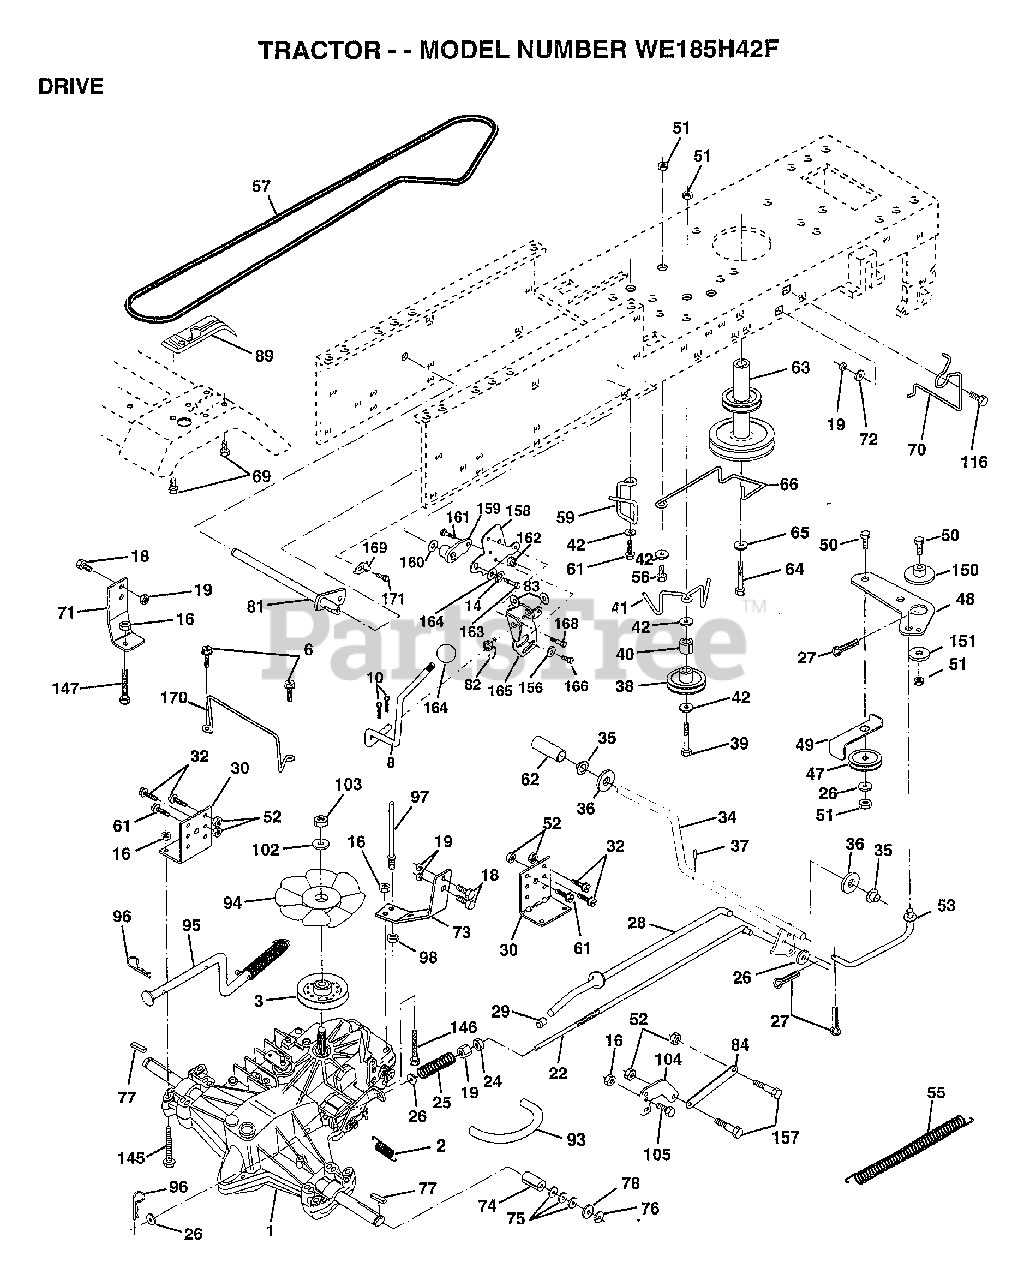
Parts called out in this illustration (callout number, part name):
2	SPRING RET BRAKE
3	PULLEY.TRANSAXLE
8	ROD.SHIFT.FENDER.ADJ.LT.CRD
10	PIN COTTER 1/8
14	LOCKWASHER
16	NUT
18	BOLT
19	NUT
21	KNOB T (1/2-HOLE)
22	ROD.BRAKE.HYDRO.
24	NUT
25	SPRING ROD LT
26	WASHER
27	COTTER PIN
28	ROD.BRAKE.PARK.LT
29	PLUNGER CAP T
30	TRANSAXLE MTG BKT
32	BOLT
34	SHAFT ASM-PEDAL F
35	NYLON BEARING
36	WASHER LT
38	FLAT IDLER PULLEY
39	BOLT
40	SPACER T
41	"KEEPER,BELT.IDLER FLAT"
42	WASHER
48	BELLCRANK.CLUTCH
49	RETAIN BELT
53	"LINK, CLUTCH T"
55	"SPRING, RETURN LT"
57	"BELT.GD DRV 82"""
59	KEEPER BELT CNTSP
61	SCREW
62	PEDAL COVER T
63	PULLEY.ENGINE
64	BOLT
65	LOCKWASHER
66	KEEPER-BELT
69	SCREW HEXWSH H-L
70	KEEPER BELT ENG
71	STRAP TORQ LH HYD
72	WASHER
73	"STRAP-TORQUE,RH"
74	SPACER SPLIT
75	WASHER
76	E-RING LT
77	SQUARE KEY
78	WASHER
81	SHAFT.ASM.CROSS
82	"SPRING,TORSION"
83	WASHER
84	LINK.TRANSAXLE.LT/YT
89	CONSOLE.SHIFT.LT
93	"LINE FUEL HYD 4"""
94	"FAN 7"" HYDRO"
96	RETAINER M
97	BOLT KEEPER RH
98	NUT
102	WASHER BELLEVILLE
104	ARM CONTROL HYDRO
105	SCREW CAP 5/16-18
116	BOLT RDHD 3/8-16
145	BOLT.HEX.FLGHD
146	BOLT.HEX.FLGHD.
147	BOLT.HEX.FLGHD
150	BUSHING.BELLCRANK.GRD.DR
151	WASHER
156	WASHER.SRRTD.5/16
157	"BOLT,SHOULDER"
158	BRKT.SHIFT.MOUNT
159	HUB.SHIFT
160	WASHER
161	BOLT T
164	WASHER.5/8X.281X10GA
165	BRKT.PIVOT.LEVER
166	SCREW.5/16-18X5/8
168	BOLT.SHOULDER.5/16-18X.561
169	PLATE.FASTENING
170	KEEPER.BELT.TRANSAXLE
171	SCREW LT
